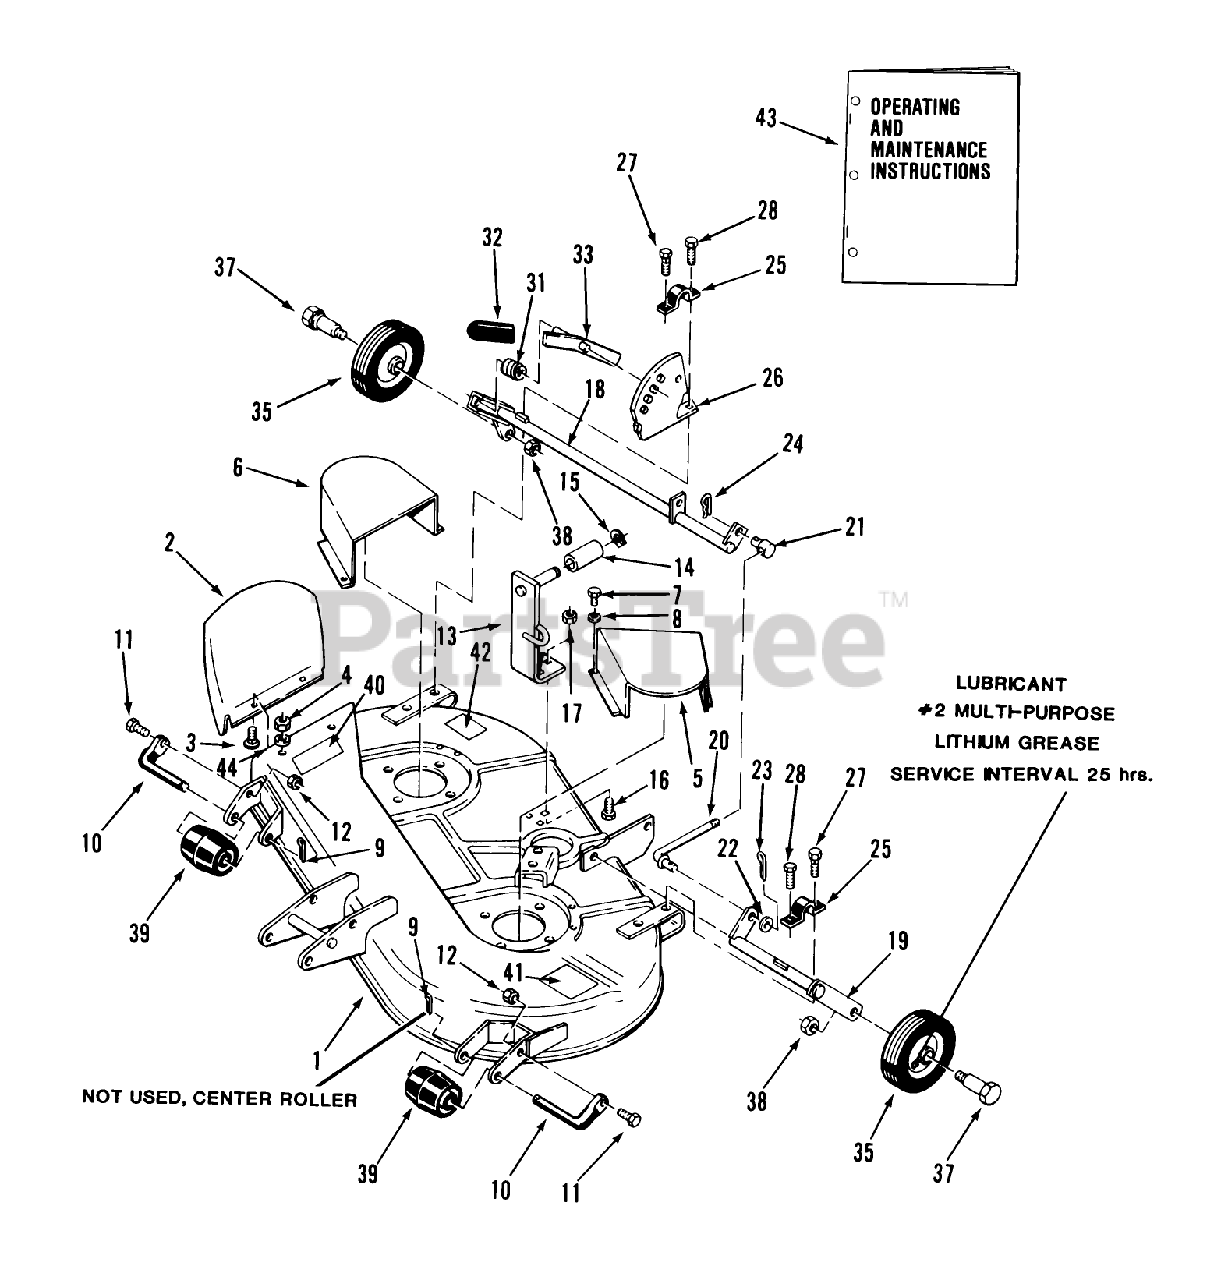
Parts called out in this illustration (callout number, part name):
6	BELT COVER-RH *R
7	Bolt
10	ROLLER-SHAFT
20	ROD CONNECTING
24	Hairpin
25	CLAMP
27	Bolt
28	Bolt
31	SPRING-COMPRESSION
35	WHEEL
37	BOLT-SHOULDER
43	Operating Maintenance Instructions
44	WASHER 5/16 SAE
